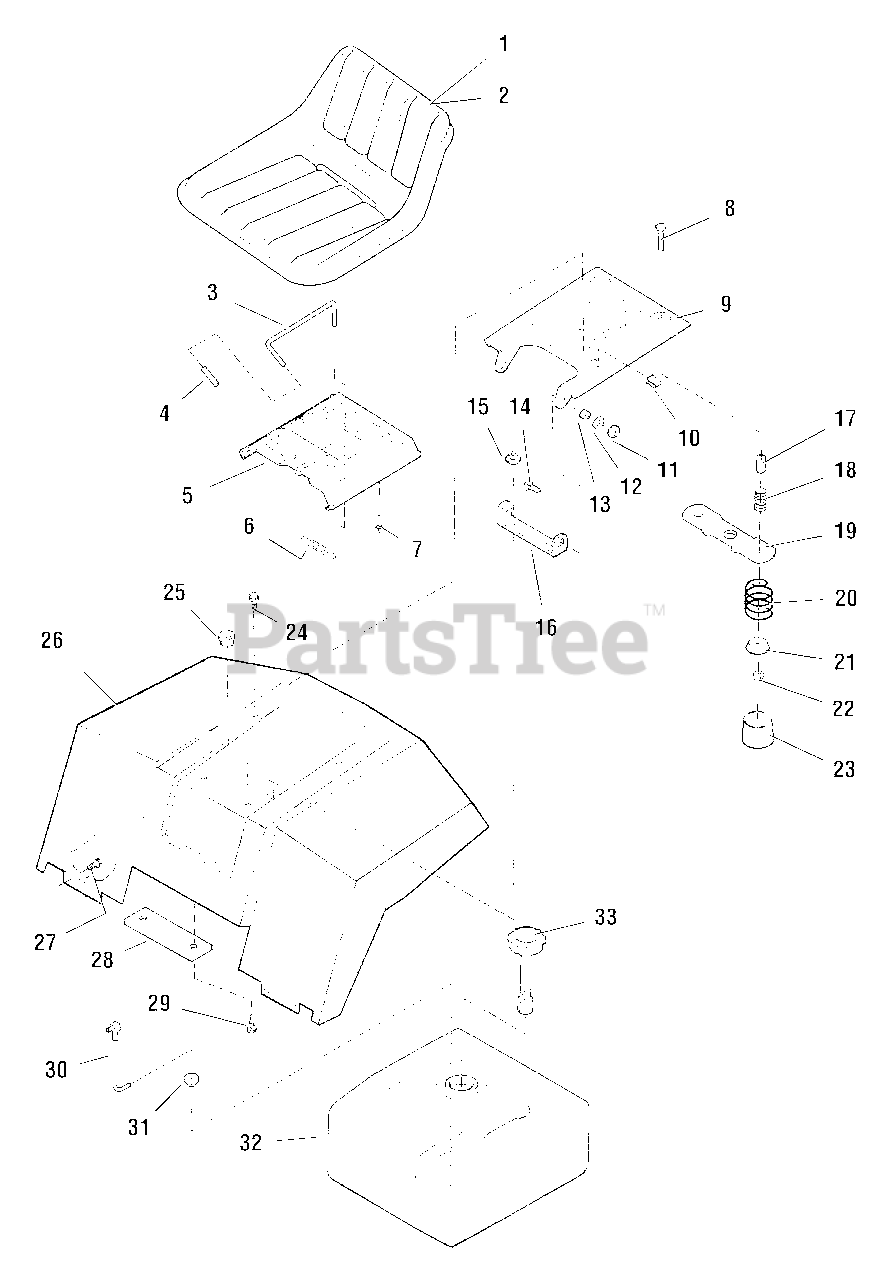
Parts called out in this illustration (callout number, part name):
1	SEAT (Incl. Ref. No. 2)
2	COVER, Seat
3	LEVER, Seat Release
4	HANDLE, Grip
5	BRACKET, Seat Slide
7	BOLT, Hex, Whizlock, 5/16-18 x 5/8
8	CARRIAGE BOLT, 5/16-18 x 2
9	SUPPORT, Seat, Pivot
10	CLIP, Speed
11	NUT, Hex Hd., Nyloc, 3/8-16
12	WASHER, Plain, 13/32
14	CARRIAGE BOLT, 3/8-16 x 1
15	NUT, Hex, Flange, Whizlock, 3/8-16
16	BRACKET, Seat, Pivot
18	SPRING, Compression
19	PLATE, Switch
20	SPRING, Compression, 2" O.D.
21	WASHER, Plain
22	NUT, Hex, Full, 5/16-18
23	COVER, Spring
24	SCREW, Taptite, 5/16-18 x 5/8
25	BUSHING, Snap
26	SEAT DECK (Orange)
26	SEAT DECK (Red)
27	SCREW, Taptite, 1/4-20 x 1/2
28	PLATE, Reinforcement
29	SCREW, Truss Hd., Torx Dr., 3/8-16 x 1
30	ELBOW & TUBE ASSY.
33	CAP, Fuel Gauge
